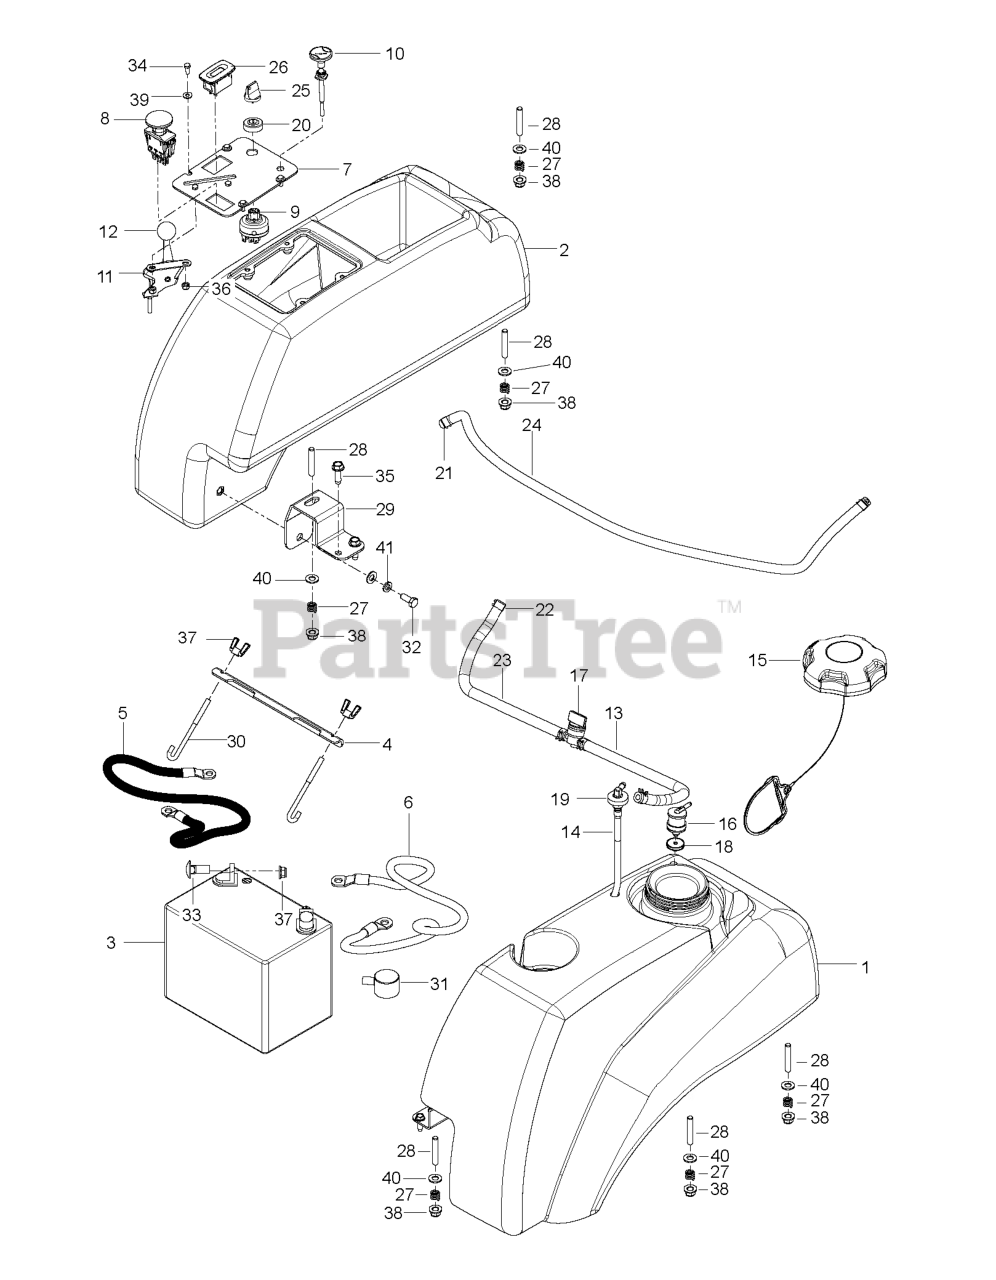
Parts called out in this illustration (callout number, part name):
1	FUEL.TANK.ASSY.LH.MZ.GRY.18
2	FENDER CONSOLE
3	BATTERY, 12 V 330 AMP
4	BRACKET.BATTERY.MOUNT.PLATED
5	CABLE.GROUND.BATT.MZ.BLACK.39"
6	CABLE.BATT.SOLENOID.MZ.RED.25"
7	PLATE.CONSOLE.BLACK
8	RP SWITCH.PTO.TERMINAL.STD.RED
9	SWITCH, IGNITION, INDAK
10	CHOKE CABLE
11	THROTTLE CABLE
12	KNOB.ROUND.BALL.BLACK
13	FUEL.HOSE.SHUT.OFF.ASM.10".10"
14	FITTING, FUEL
15	CAP, FUEL
16	VALVE.FUEL.CHECK
17	FUEL VALVE
18	GROMMET, CHECK VALVE
19	RUBBER GROMMET
20	CAP IGNITION NUT
21	CLAMP, HOSE
22	HOSE CLAMP
23	HOSE.1/4".LOW.PERM.FUEL.LN.10"
24	HOSE.3/16".VAPOR.LINE.27"LGTH
25	KEY, IGNITION
26	GUAGE.SRVCMNDR.HRMTR.
28	STUD, 5/16C
29	SUPPORT.PNT.TANK.FRONT.STAMPED
31	COVER.TERMINAL.BATTERY
32	HCS 5/16C X 3/4
33	BOLT 5/16C X 3/4" CARRIAGE
34	HCS #10-24 X 1/2
35	SCREW
36	NUT 10-24 NYLOC
37	WING NUT 1/4
38	5/16-18 NYLOC FLANGE NUT
40	WASHER
41	WASHER.LOCK.HVY.HLCL.SPR.5/16
